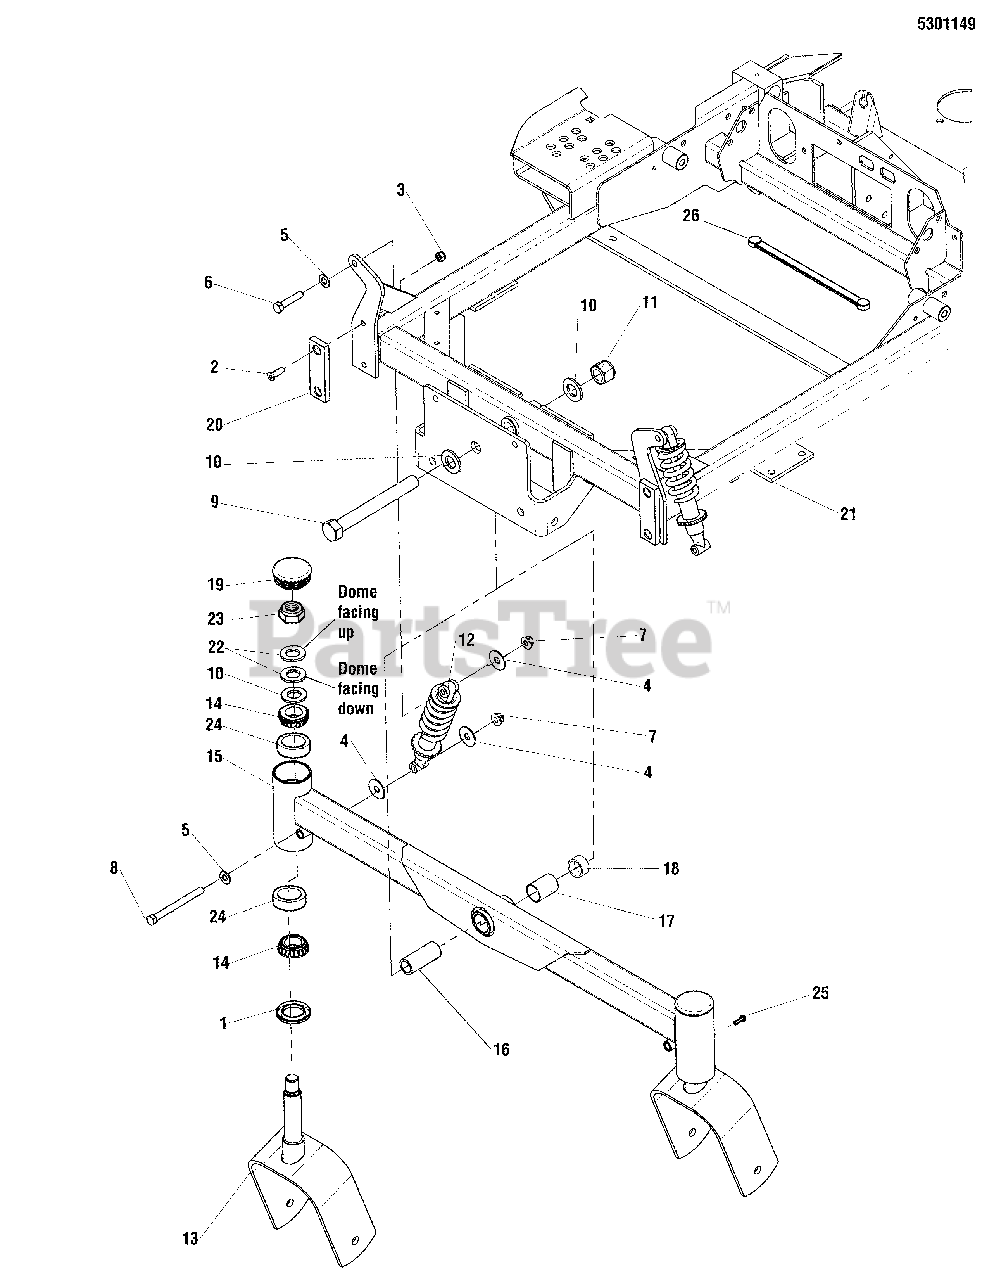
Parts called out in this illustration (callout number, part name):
1	SEAL, GREASE
2	SCREW, 5/16-18 X 1 PHILLIPS HD, BZ
3	NUT, 5/16-18 HEX NYLON LOCK
4	WASHER, 3/8 FENDER
5	WASHER, 3/8 SAE
6	BOLT, 3/8-16 X 1-3/4 GD5
7	NUT, 3/8-16 HEX NYLOCK FLANGE
8	BOLT, 3/8-16 X 4 GD5 YZ
9	BOLT, 3/4-16 X 6-1/2 YZ GD5
10	WASHER, 3/4" SAE
11	NUT, 3/4-16 HEX NYLON LOCK
12	SHOCK, SPRING ASSEMBLY
13	WELD, CASTER YOKE, IS500Z - ORG
14	BEARING, TAPERED ROLLER, 1"
15	WELD, FRONT PIVOT, CITATION - ORG
16	SPACER, .75 X 1.00 X 2.38
17	PIVOT BEARING, 1.00" X 1.125" OD X 1.50"
18	PIVOT BEARING, 1.00 X 1.125 OD X .50
19	CAP, LOW PROFILE, STEEL
20	PAD, FRICTION, .375 X 1.25 X 4.00
21	WELD, IS500 MAIN FRAME - ORG
22	WASHER, BELLEVILLE - 1.500 X .755
23	NUT, 3/4-16, HEX JAM NYLON LOCK
24	BEARING CUP
25	BOLT, 1/4-28 X 1/2, GD5 YZ
26	STRAP-BLACK RUBB
